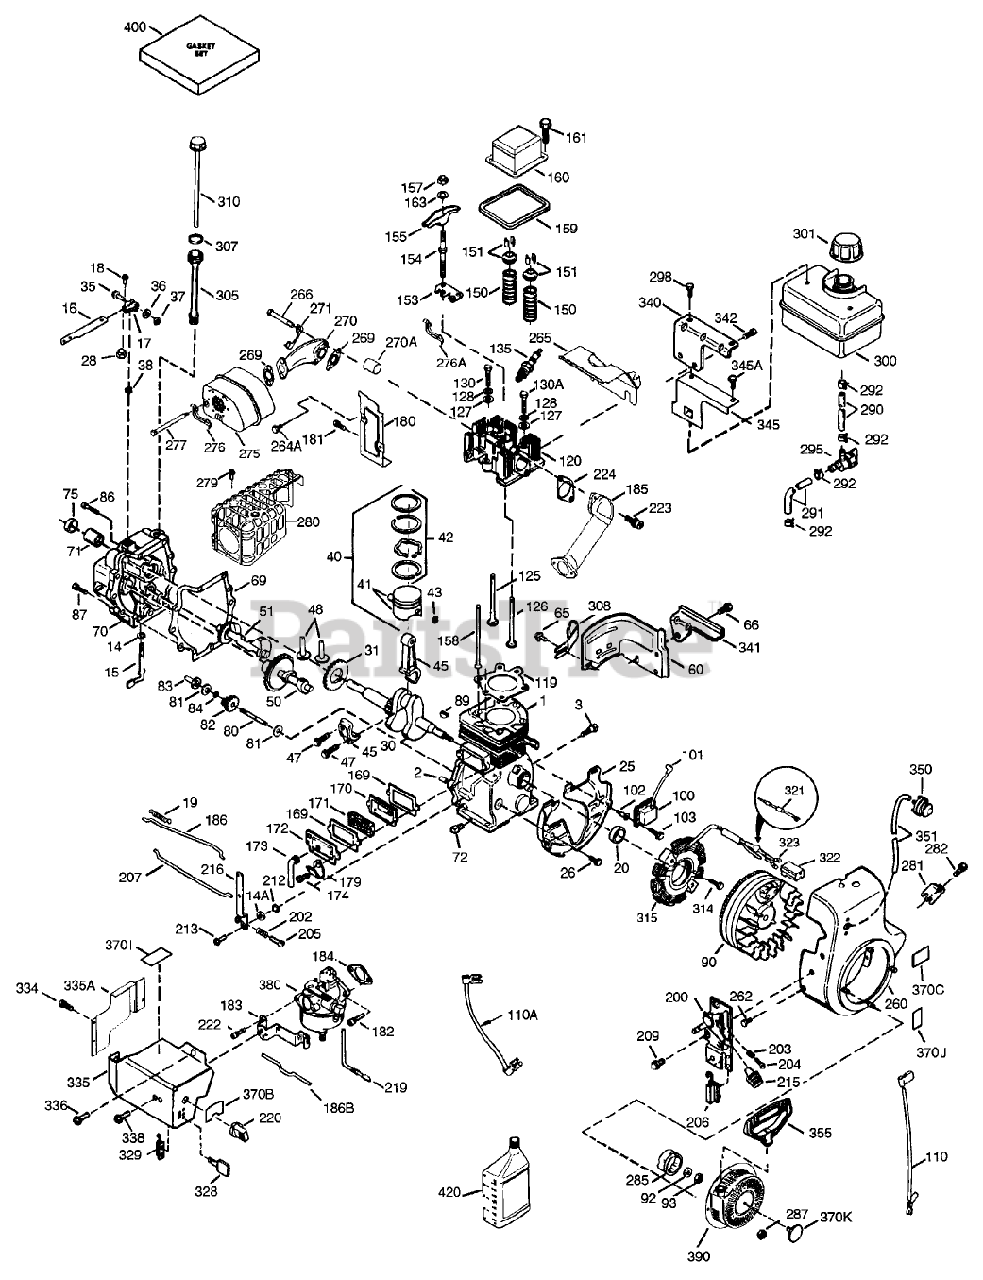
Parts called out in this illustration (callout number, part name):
1	Cylinder (Incl. 2, 20, 72 80)
2	Pin-Dowel
3	Screw (1/4-20x1/2)
14	Washer-Flat
14A	Washer
15	Governor Rod (Incl. Ref.#14 38)
16	Governor Lever
17	Clamp-Lever, Governor
18	Screw (T-15, 8-32x7/16)
19	Throttle Spring
20	Seal-Oil
25	Baffle-Housing, Blower
26	Screw (1/4-20x19/32)
28	Nut-Lock
30	Crankshaft
31	Counterbalance Gear
35	Screw
36	Washer-Lock
37	Nut-Lock
38	Ring-Retaining
40	Piston Pin and Ring ASM (STD)
40	Piston Pin and Ring ASM (.010)
40	Piston-Pin Ring Set (.020" OS)
41	Piston Pin Ass-y(Std.)(Incl. 43)
41	Piston Pin Ass-y (.010" OS)(Incl. 43)
41	Piston Pin Ass-y.(.020" OS)(Incl. 43)
42	Ring Set (STD)
42	Ring Set (.010)
42	Ring Set (.020)
43	Retaining Ring-Piston Pin
45	Connecting Rod ASM (Incl. Ref. #47)
47	Bolt-Rod, Connecting
48	Lifter-Valve
50	Camshaft
51	Counterbalance Weight
60	Extension-Housing, Blower
65	Screw (10-24 x 9/16)
66	Screw (1/4-20x19/32)
69	55072/75/86/89 TWO
70	Cylinder Cover (Incl. Ref. #14, 15, 38, 71, 75)
71	2025A77 WIZARD ROTA
72	Plug-Drain, Oil (SQH 1/4-18)
75	Seal-Oil
80	Governor Shaft
81	Washer
82	Gear-Asm Governor
83	Governor Spool
84	Ring-Retaining
86	Screw (1/4-20x1-3/16)
87	Screw (1/4-20x1-11/16)
89	Key-Flywheel
90	Flywheel (W/Ring Gear)
92	Washer-Belleville
93	Nut-Flywheel
100	Solid State ASM
101	Cover-Spark Plug
102	Stud-Mounting, Solid State
103	Screw (T-15, 10-24 x 15/16)
110	Wire-Ground
110A	Wire-Ground (Green, 5.5)
119	Cylinder Head Gasket
120	Cylinder Head
125	Valve-Exhaust (STD)
125	Valve-Exhaust (1/32)
126	Valve-Intake (STD)
126	Intake Valve (1/32)
127	Washer-Flat
128	Washer-Belleville
130	Screw (5/16-18 X 2-1/2)
130A	Screw (T-30, 1/4-20x15/32)
135	Spark Plug-Resistor (R N 4C)
150	Spring-Valve
151	Keeper-Spring, Valve
153	Guide-Rod, Push
154	Stud-Arm, Rocker
155	Arm-Rocker
157	Nut-Jam
158	Rod-Push
159	Gasket-Cover, Rocker Arm
160	Cover-Arm, Rocker
161	Screw
163	Washer
169	Gasket-Cover, Valve
170	Body-Breather
171	Element-Breather
172	Cover-Valve
173	Tube-Breather
174	Screw
179	Retainer Clip
180	Extension-Housing, Blower
181	Screw (10-24 x 9/16)
182	Screw (T-30, 1/4-20 X 27-32)
183	Bracket-Choke
184	Gasket-Carburetor To Intake Pipe
185	Pipe-Intake
186	Governor Link
186B	Spring-Choke
200	Bracket-Control (Incl. Ref. #203, 204 and 206)
202	Compression Spring
203	Spring-Compression
204	Screw (T-10, 5-40x7/16)
205	Screw
206	Terminal
207	Choke Link
209	Screw (10-32 x 1/2)
212	Bushing
213	Screw
215	Knob-Control
216	Lever-Adjusting
219	Rod-Choke
220	Knob-Control
222	Screw (10-32 x 1/2)
223	Screw (T-30, 5/16-18 X 7/8)
224	Gasket-Pipe
260	Blower Housing
262	Screw
264A	Screw (1/4-20 X 5/8)
265	Cover-Head, Cylinder
266	Screw (5/16-18 X 1-9/32)
269	Gasket-Manifold, Exhaust
270	Exhaust Manifold
270A	Liner-Port, Exhaust
271	Plate-Locking
275	Muffler
276	Plate-Locking
276A	62513 SNWTHWR W/284
277	Screw (5/16-18 X 4-1/2)
279	Screw
280	Cylinder (Incl. 2, 20 150)
281	Screw
282	Screw (8-32 x 3/8)
285	Cup-Starter
287	Nut and Lock Washer (1/4-28)
290	Line-Fuel (8.62)
291	Line-Fuel
292	Clamp-Line, Fuel
295	Valve-Shut Off, Fuel
298	Screw (1/4-15x7/8)
300	Fuel Tank (Incl. 292 301)
301	Cap-Fuel
305	Tube-Fill, Oil
307	O-Ring
308	Clip-Tube, Fill
310	Dipstick
314	Screw (1/4-20 x 3/4)
315	Alternator Coil (3/5)(Incl. 321-323)
321	Diode
322	Body-Connector
323	Terminal
328	Key-Ignition
329	Terminal
334	Screw (8-32 X 5/16)
335	Carburetor Cover
335A	Cover-Carburetor
336	Screw (10-32x1/2)
338	Screw (10-32 x 1/2)
340	55073/76/87/90 SNWT
341	Bracket-Fuel Tank
342	Screw (5/16-18 X 7/8)
345	Baffle-Heat
345A	Screw (5/16-18 X 1-9/32)
350	Primer ASM
351	Line-Primer
355	Handle-Starter, Mitten Grip
370B	Control Decal
370C	Decal-Primer, International Symbol
370I	Decal-Warning (Bilingual)
370J	Throttle Decal
370K	Decal-Tecumseh Logo for Top of Recoil Starter
380	Carburetor (Incl. Ref.# 184)
390	Starter-Rewind
400	Gasket Set
420	Oil-Engine (SAE 5W30)
